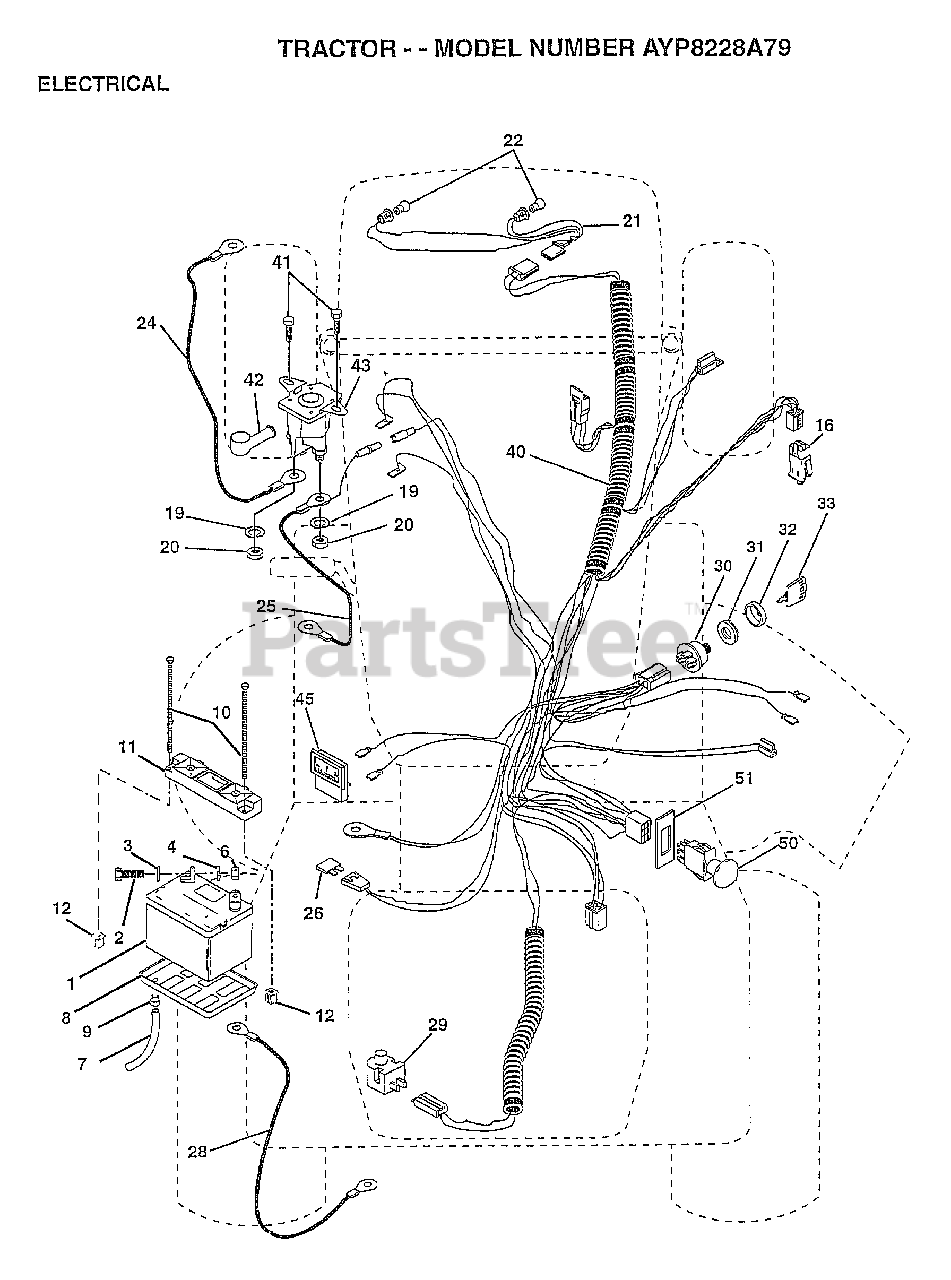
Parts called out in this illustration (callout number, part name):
2	BOLT LT
3	LOCKWASHER
4	WASHER
7	"DRAIN TU T, BATT"
8	"TRAY T, BATTERY"
9	HOSE CLAMP T
11	HOLDDOWN BATTERY
16	SWITCH INTERLOCK
20	NUT
21	"HARNESS,LIGHT SOC"
22	HEADLAMP BULB
24	CABLE.BATY.22.RED
25	CABLE.BATRY.4GA.
26	FUSE HYT
28	"CABLE BATTERY,GRD"
29	SWITCH SEAT
30	SWITCH IGN 4POS
31	NUT IGNITION
32	COVER KEY SWITCH
33	KEY
40	HARNESS IGNITION
41	SCREW
45	AMMETER
50	PTO SWITCH.BLK
51	RING RETAIN PTO
